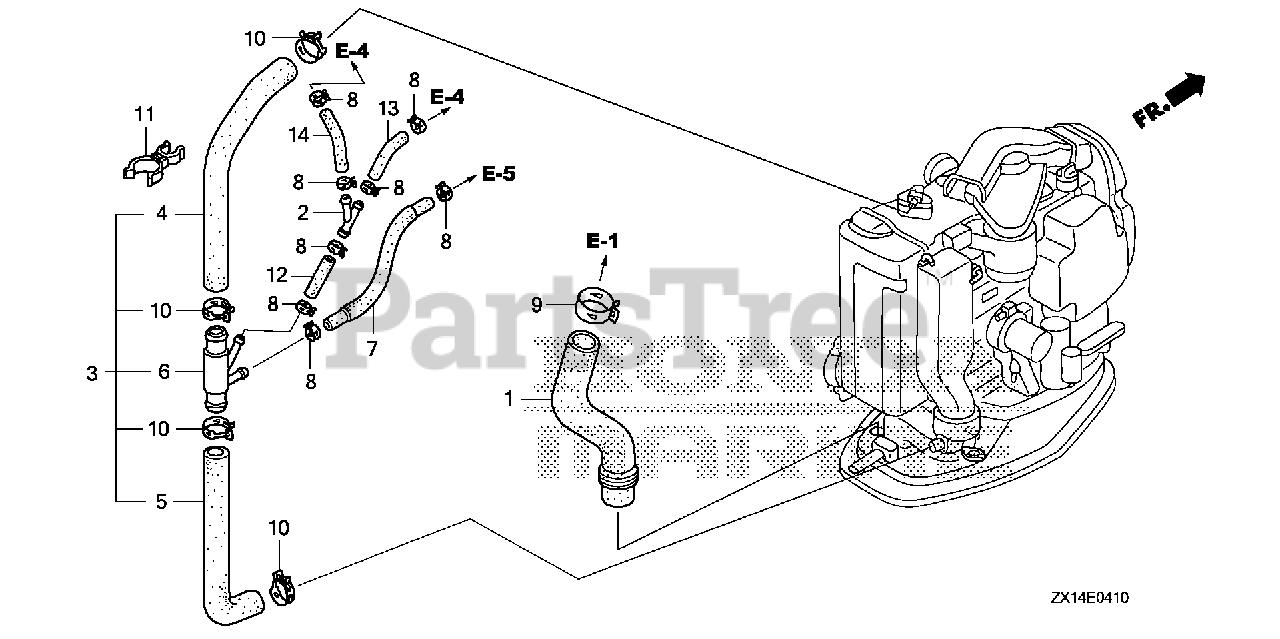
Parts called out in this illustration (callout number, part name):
2	JOINT, FUEL TUBE
3	TUBE, WATER RELIEF
4	TUBE A, WATER RELIEF
5	TUBE B, WATER RELIEF
6	JOINT, FOUR-WAY
7	TUBE E, WATER
8	CLAMP, TUBE (D10.5)
9	CLAMP, TUBE (D32.5)
10	CLAMP, TUBE (D25.0)
11	CLAMP, WATER TUBE
12	BULK HOSE, VACUUM (7X3000) (7X75)
13	BULK HOSE, VACUUM (7X3000) (7X90)
14	BULK HOSE, VACUUM (7X3000) (7X120)
